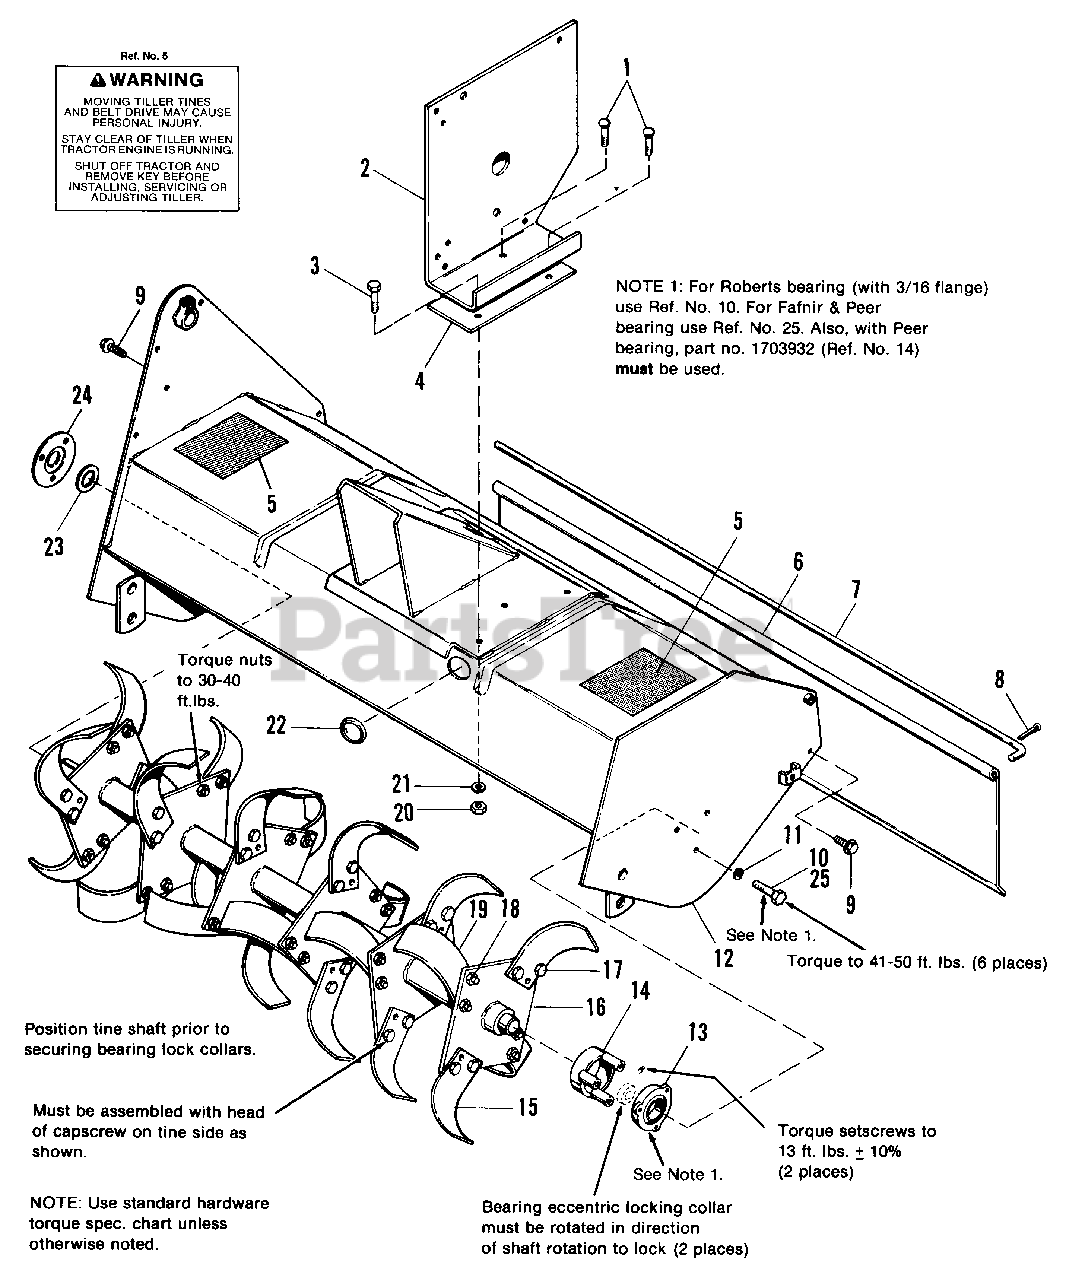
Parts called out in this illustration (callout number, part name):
1	CARRIAGE BOLT, 5/16-18 x 1
2	SUPPORT ASSY.
3	CAPSCREW, Hex Hd., 5/16-18 x 1
4	SHIM, Plate
5	DECAL, Safety
7	ROD, Deflector
8	COTTER PIN, 3/32 x 1
9	SCREW, Thread Forming, Taptite, 3/8-16 x 1-1/4
10	CAPSCREW, Hex Head, 3/8-16 x 1-3/4
11	LOCKWASHER, 3/8
12	HOUSING ASSY.
13	FLANGE, Bearing Kit (Incl. Ref. No. 14)
14	GUARD ASSY., Trash
15	TINE, L.H.
16	SHAFT ASSY., Tine
17	CAPSCREW, Hex Hd., 3/8-16 x 1
18	LOCKNUT, Hex, 3/8-16
19	TINE, R.H.
20	NUT, Hex, Full, 5/16-18
21	LOCKWASHER, 5/16
22	BUTTON, Plug
24	RETAINER, Seal
25	CAPSCREW, Hex Hd., 3/8-16 x 1-1/4 (Used with Fafnir & Peer Bearings)
